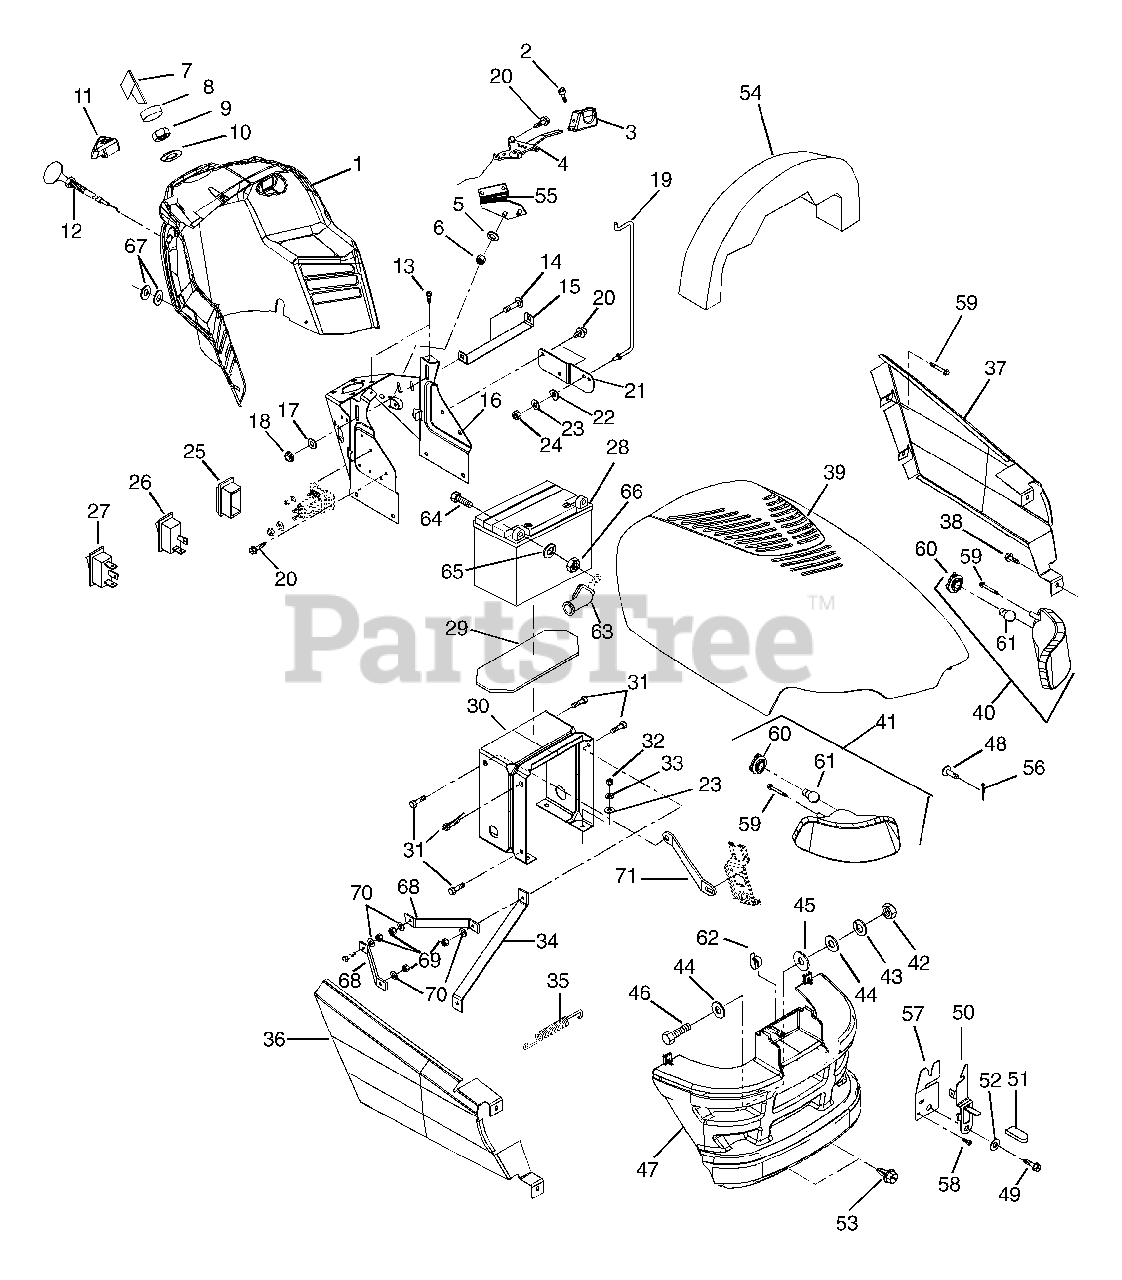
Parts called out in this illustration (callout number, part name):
1	DASH
1	DASH-VENTED
2	SCR-SET 10-24X.38 UNC-3A
3	KNOB, THROTTLE
4	THROTTLE CONTROL- TEC/B&S
5	WSHR-FL-STL .323X.625X.062 YWZ
6	@NUT-LK-CTR .25-20 YWZC
7	IGNITION SWITCH KEY
8	CAP - IGNITION SWITCH
9	NUT- PANEL .562-24 GRECO
10	WSHR-LK-INT .625X.045 YWZC
11	PTO SWITCH ASSEMBLY
12	CHOKE CABLE
13	SCR-TAP 10-24X.484 HWH TR
14	@BLT-RDHDSQNK .31-18X.75 G5YZ
15	HOLDDOWN - BATTERY
16	SUPPORT - DASH - TOP
17	WSHR-FL-STL .323X.625X.062 YWZ
18	@NUT-LK-NYL .312-18 YWZC
19	ROD - HOOD PROP
20	@SCR-TAP .25-20X.37 HWH YWZ TR
21	MOUNT - PROP ROD
22	WAVE WASHER .390X.655X.110
23	@WSHR-FL-STL.312X.734X.065 YWZ
24	@NUT-LK-CTR .25-20 YWZC
26	SWITCH - LIGHT
27	SWITCH - CRUISE
28	BATTERY W/TUBE
29	RUBBER PAD
30	SUPPORT DASH BASE
31	@SCR-TAP .31-18X.50 HWH TR YWZ
32	@NUT-HEX .31-18 YWZC
33	WSHR-LK .312X.097 HVY YWZC
35	SG-TENS .035X.45X2.75 WLD 3.5
36	PANEL, R.H
37	PANEL, L.H
38	SCR-TAP 12-16X.500 HI-LOTPHBL
39	HOOD WITH DECALS
39	HOOD W/DECALS&VENTS
40	HEADLIGHT- LH
41	HEADLIGHT- RH
42	@NUT-HEX .31-18 YWZC
43	WSHR-LK .312X.097 HVY YWZC
44	WSHR-FL-STL .328X1.0X.094 YWZC
45	WSHR-FL-NYL .390X1.000X.062
46	@BLT-HEX .31-18X1.00 GR5 YWZC
48	PIN, CLEVIS .243/.248X1.50 YWZ
49	SCR-TAP 12-24X.50 HWH TR BLACK
50	HOOD LATCH
51	GRIP .062 X .375 X 1.000 RE
52	WSHR-FL-STL .281X1.250X.048 BL
53	SCR-TAP .312-18X.50 HWH TR BL
54	BAFFLE, FOAM (INTEK V TWIN)
54	HOOD - ARIENS
55	BRACE-THROTTLE CONTROL
56	@PIN-CTR .09X.75 EXTPRSQCT YWZ
57	LOCATOR- HOOD
58	SCR-TAP 10-12X.50 CRPH PL A BL
59	SCR-TAP 10-24X.75 HWH TR YWZC
60	LAMP SOCKET
61	HEADLIGHT BULB, 1156
62	CLIP-HARNESS TINNERMAN
63	INSULATOR
64	@BLT-HEX .25-20X.75 GR5 YWZC
65	WSHR-LK .250X.077 HVY YWZC
66	@NUT-HEX .25-20 YWZC
67	WSHR-FL-STL .219X.500X.049BLZC
68	BRACKET-STEERING ASSEMBLY
69	@NUT-LK-NYL .312-18 YWZC
70	@WSHR-FL-STL.344X.688X.065YWZC
71	BRACKET-STEERING ASSEMBLY
